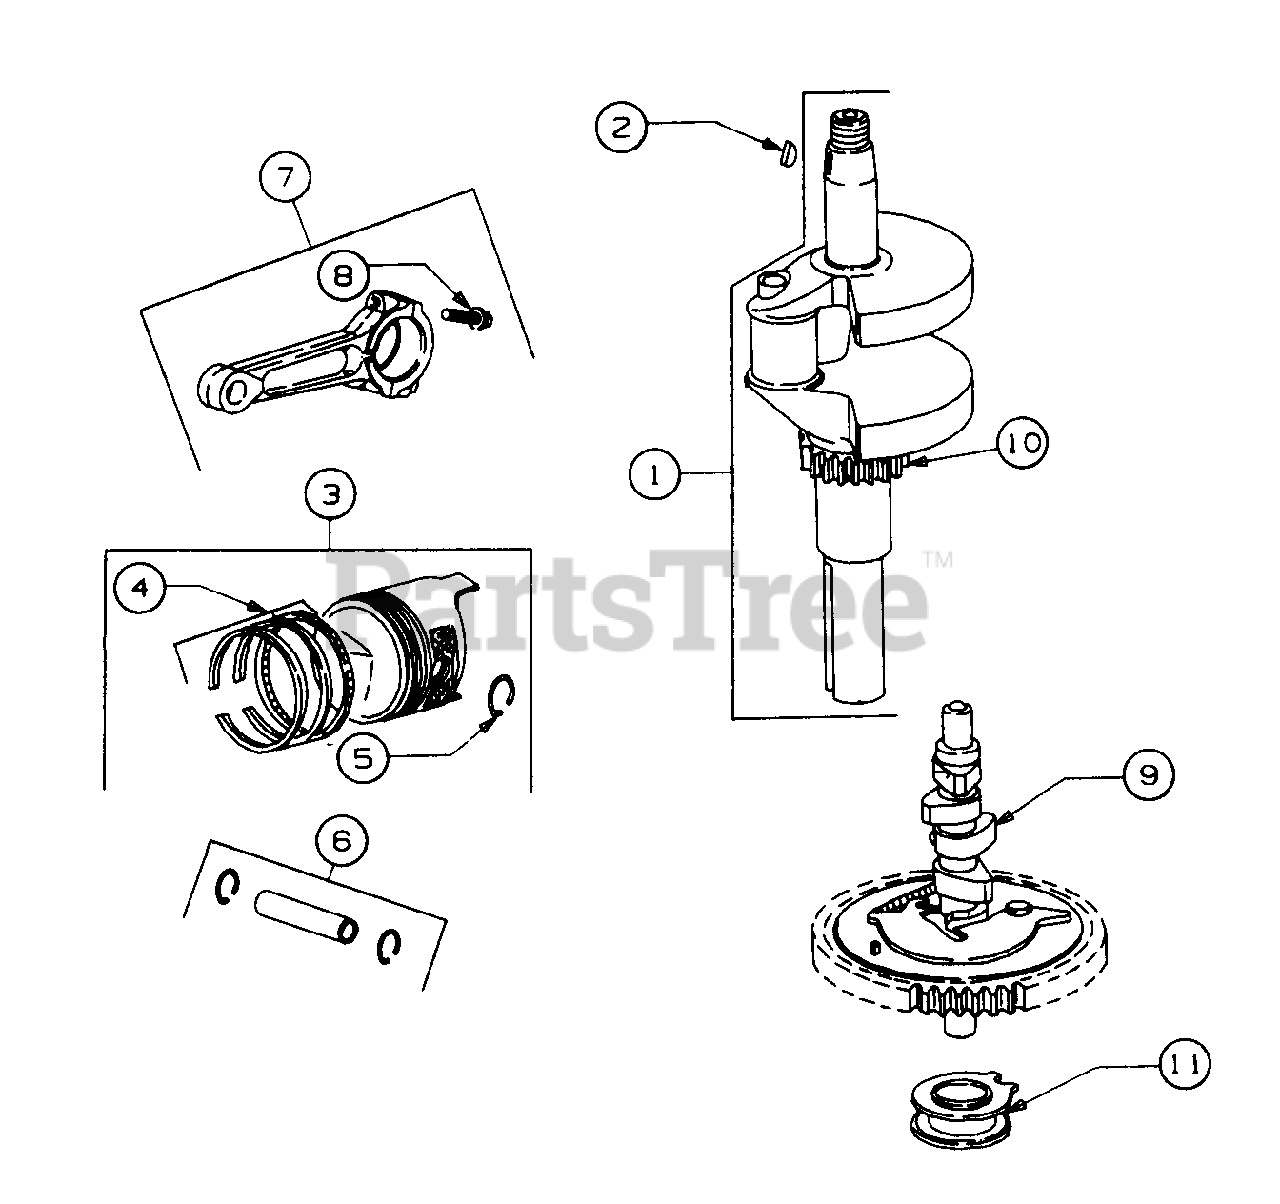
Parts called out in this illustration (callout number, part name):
1	Crankshaft
2	Key, Flywheel
3	Piston Assy
4	Ring Set, Piston
5	Lock, Piston Pin
6	Pin Assy, Piston
7	Rod Assy, Connecting
8	Screw, Connecting Rod
9	Gear, Cam
10	Gear, Timing
11	Slider, Governor
